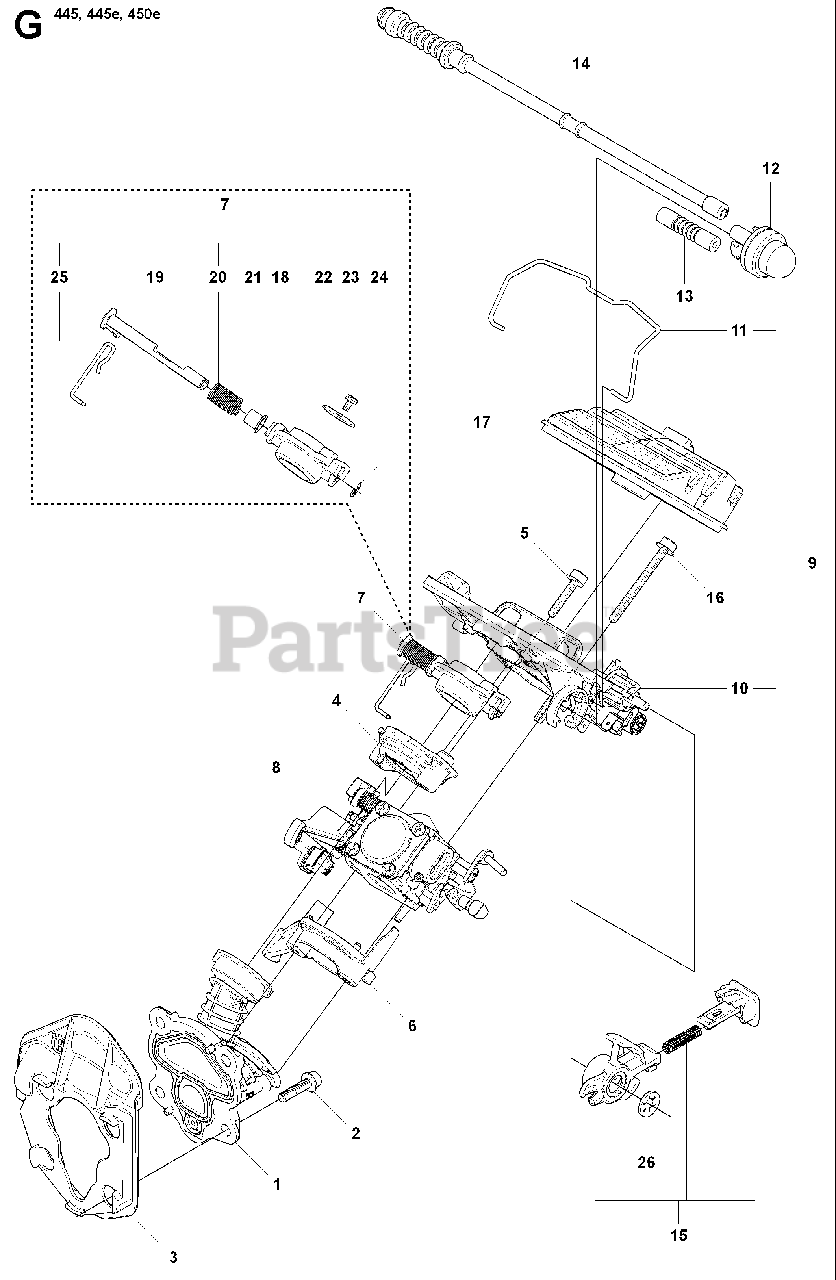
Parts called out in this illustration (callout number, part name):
1	INLET PIPE ASSY
3	INTERMEDIATE WALL
8	%CARBURETOR
9	%FILTER HOLDER ASSY
12	AIR PURGE BUBBLE
13	HOSE
14	RP RETURN HOSE
17	AIR FILTER - NYLON (80)
17	AIR FILTER - NYLON (44)
17	AIR FILTER - FELT
19	SHAFT ASSY
26	LOCK WASHER
